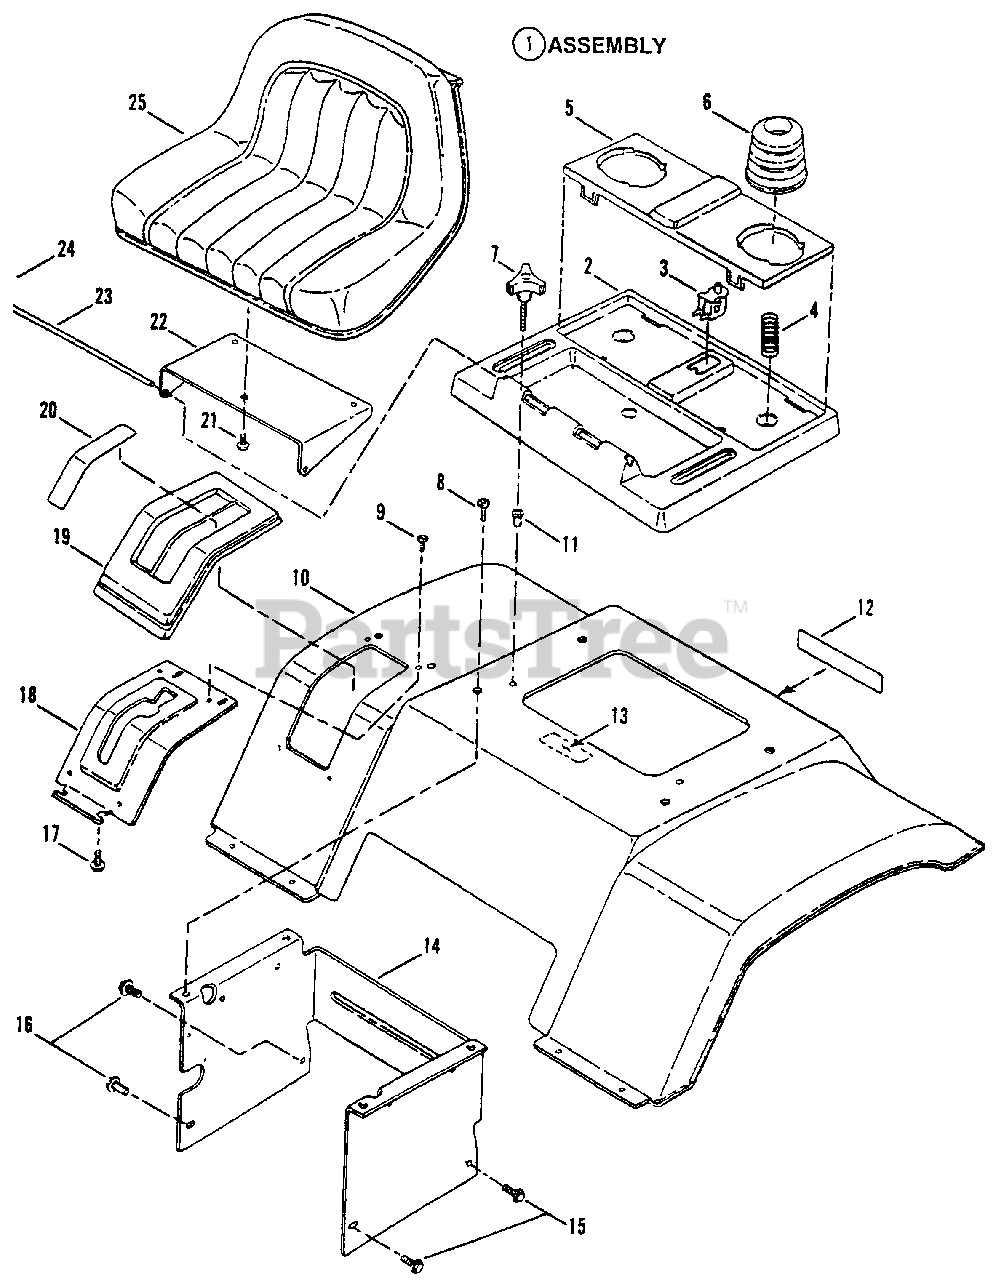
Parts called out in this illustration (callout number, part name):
1	ASSEMBLY, Seat Support
2	SUPPORT, Seat
3	SWITCH, Seat
4	SPRING
5	HOLDER, Cushion
6	CUSHION, Seat
7	KNOB, Seat Adjustment
8	SCREW, 5/16-18 x 5/8" Truss Head, Torx
9	SCREW, 1/4-20 x 5/8" Hex Washer Head, Self-Tapping
10	PAN, Seat (Fender)
11	RIV-NUT, 5/16-18
12	DECAL - BLACKHAWK, Molded Logo
13	DECAL - CAUTION, Battery Location
14	SUPPORT, Fender
15	SCREW, 5/16-18 x 5/8" Hex Washer Head, Swage Form
16	SCREW, 5/16-18 x 1 1/4" Hex Washer Head, Swage Form
17	SCREW, #10-16 x 1/2" Hex Washer Head, Self-Tapping
18	DETENT, Shift
19	COVER, Shift
20	DECAL, Shift Cover
20	DECAL,
21	BOLT, 5/16-18 x 1/2" Hex Flange Lock
22	BRACKET, Seat Support
23	ROD, Seat Hinge
24	HAIR-PIN, 3/32 x 1 1/2"
25	SEAT, Operator's
